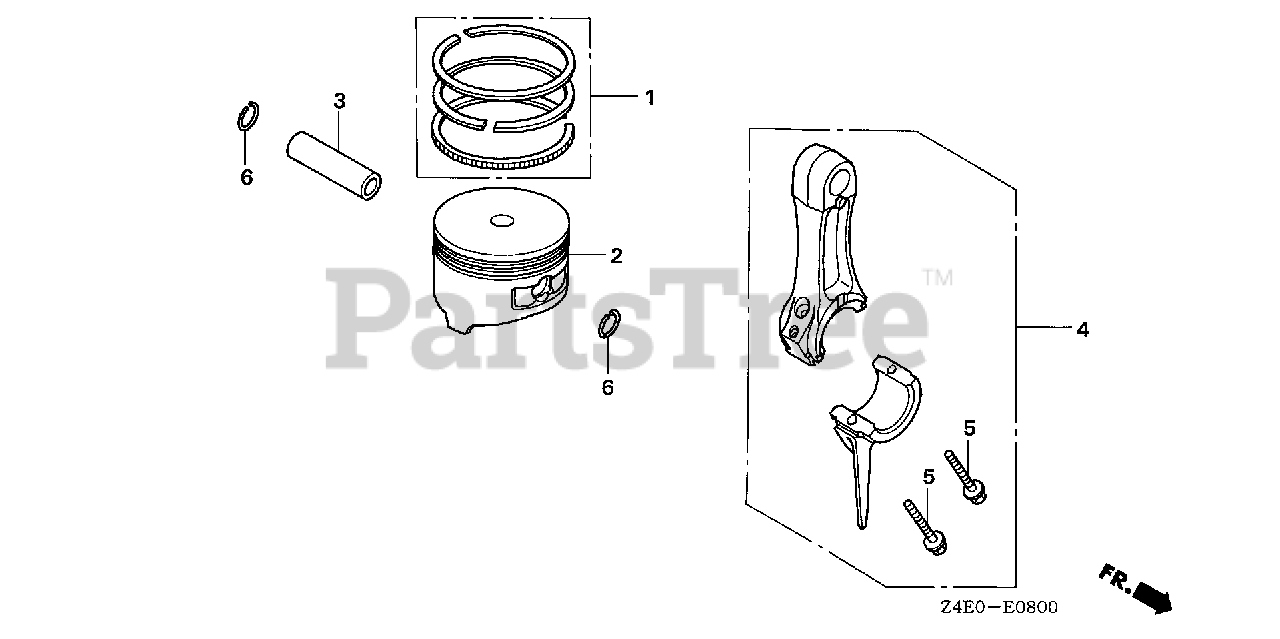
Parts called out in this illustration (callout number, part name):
1	RING SET, PISTON
3	PIN, PISTON
4	ROD ASSY., CONNECTING
4	ROD ASSY., CONNECTING (UNDER SIZE)
5	BOLT, CONNECTING ROD
6	CLIP, PISTON PIN (13MM)
